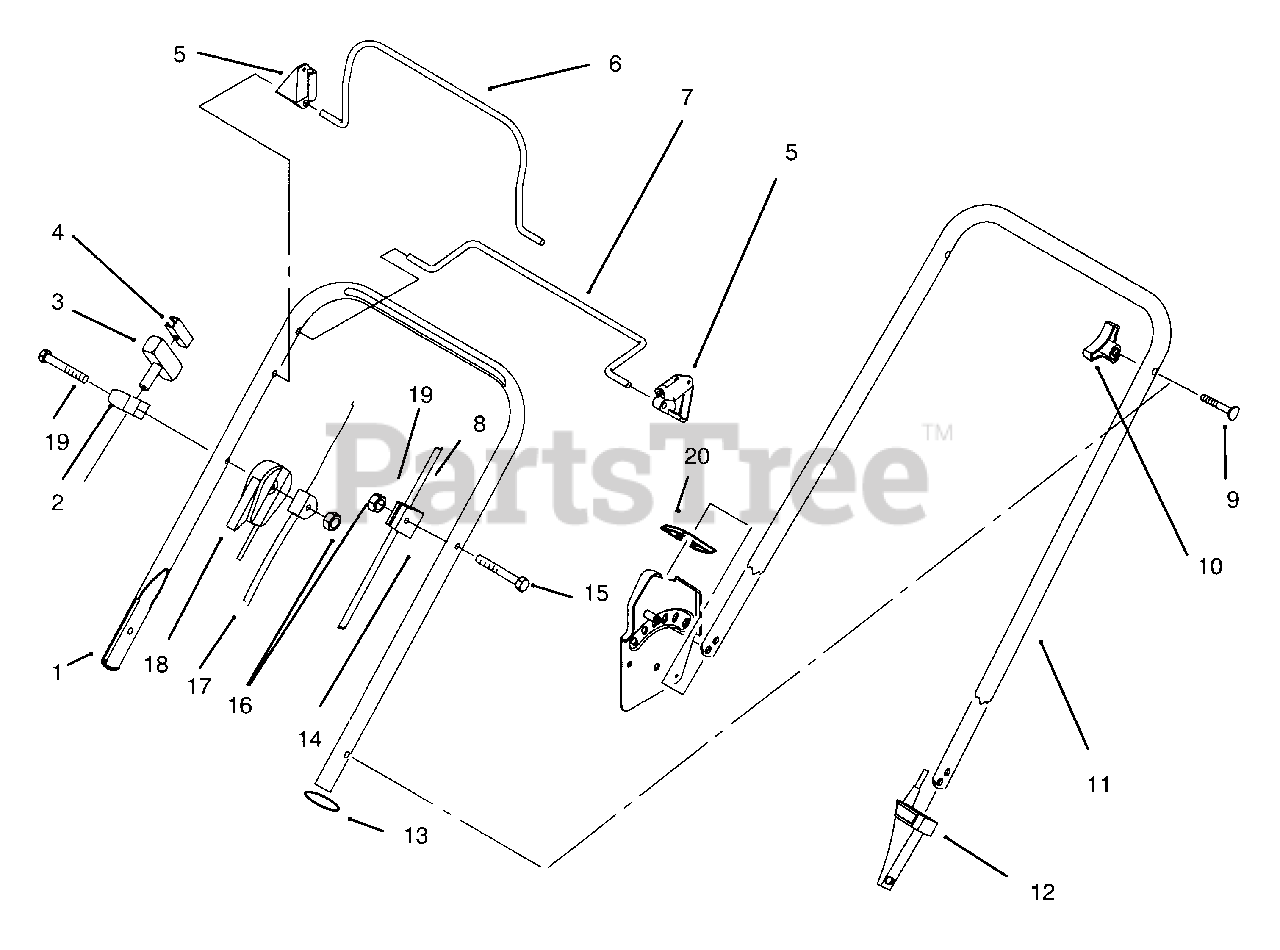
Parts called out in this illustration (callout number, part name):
1	Handle-Upper
2	Guide-Rope
3	Handle-Starter
4	Clip-Rope Insert
5	Stop-Pivot
6	Bail-Brake
7	Bail-Control (Model No.10302 & 10310 Only)
8	Cable-Traction
9	Screw-Handle
10	Knob-Handle
11	Handle-Lower
12	Anchor Cable, (Lower)(Model No.10302 & 10310 Only)
13	Tie Strap
14	Anchor-Cable, (Upper)(Model No.10302 & 10310 Only)
17	Cable-Brake
18	Cable-Throttle
20	Handle-Guard
